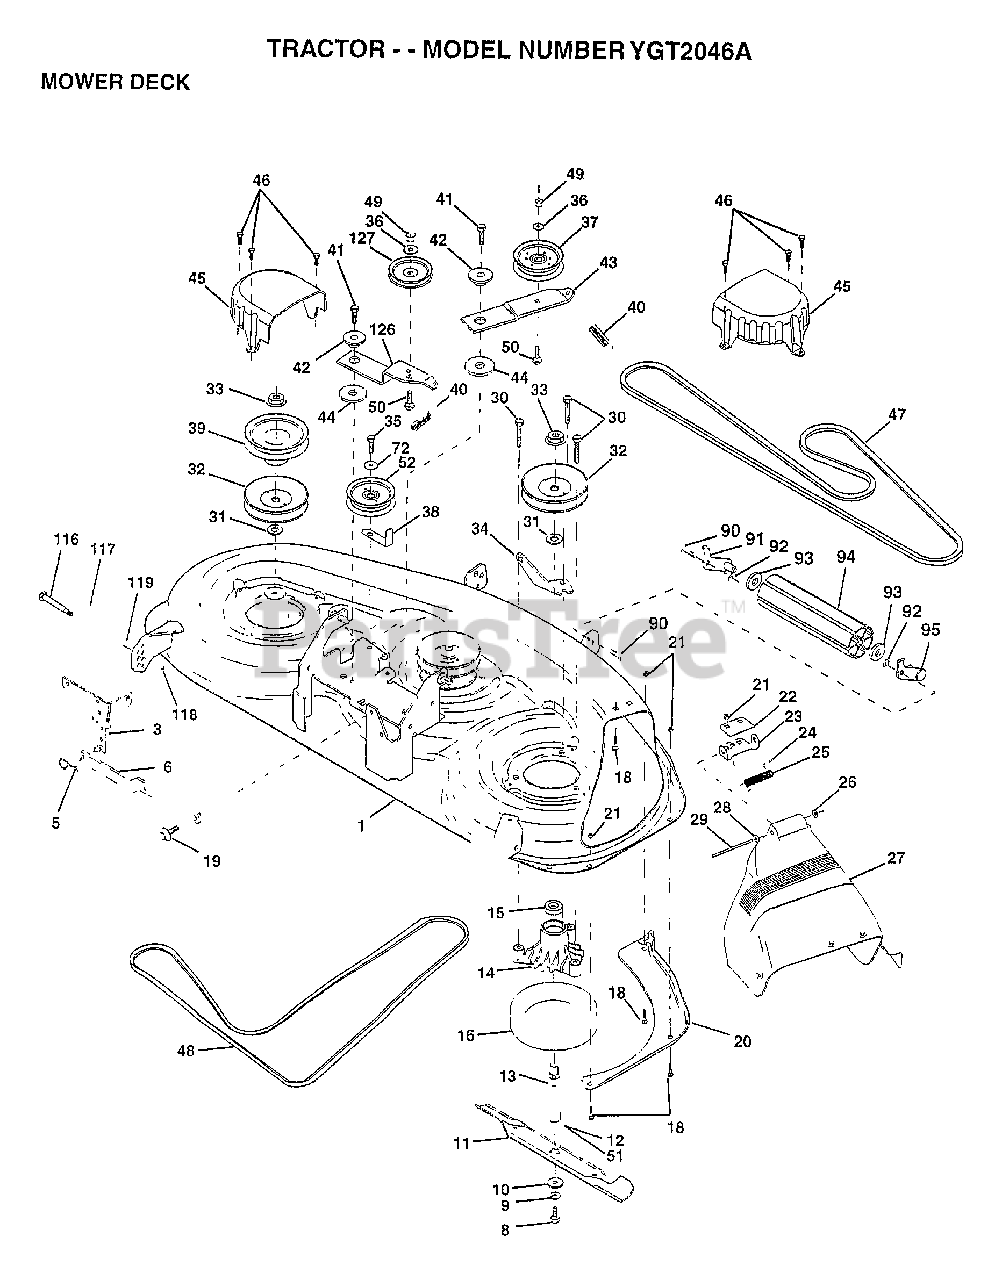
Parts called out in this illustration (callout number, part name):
1	"MOWER ASM 46"""
3	BRKT.ASM.SW.44/50
8	BLADE BOLT
10	WASHER.HARD.BLADE
12	BEARING.BALL
13	SHAFT.ASM.W/BRNG
14	HOUSING.MAND.44.V
15	BEARING
16	STRIPPER RND MWR
18	BOLT
19	BOLT SHD 5/16-18
20	BAFFFLE.VORTEX.46
22	STIFFENER BRKT
23	DEFLECTOR BRKT
24	CAP-SLEEVE LT
25	SPRING TORSION
26	NUT PUSH M
27	SHIELD DEFLECTOR
28	WASHER
29	HINGE ROD
31	WASHER
32	PULLEY.MAND.36/46
34	ANCHOR.SPRING.46
35	SCREW LT
36	WASHER
37	FLAT IDLER PULLEY
38	"KEEPER BELT,IDLER"
39	PULLEY.DRV.DCK.46
40	"SPRING.SEC.44""VEN"
41	SCREW
42	SPACER RETAINER
43	ARM.IDLER.DECK.46
44	HARDENED WASHER
45	COVER.MANDREL.46
46	SCREW.1/4-20X5/8
47	BELT-V.SEC.46.KEL
48	BELT V PRIM 50
50	BOLT.3/8-16X1.50
51	WASHER.FELT.
52	"PULLEY IDLER,FLAT"
72	WASHER HYT
90	BOLT
92	NUT
93	WASHER
116	BOLT.SHOULDER
117	WHEEL GAGE DONUT
118	LOCKNUT
119	WASHER
120	WASHER
126	ARM.IDLER.PRIM.46
127	PULLEY.IDLER.4.25
